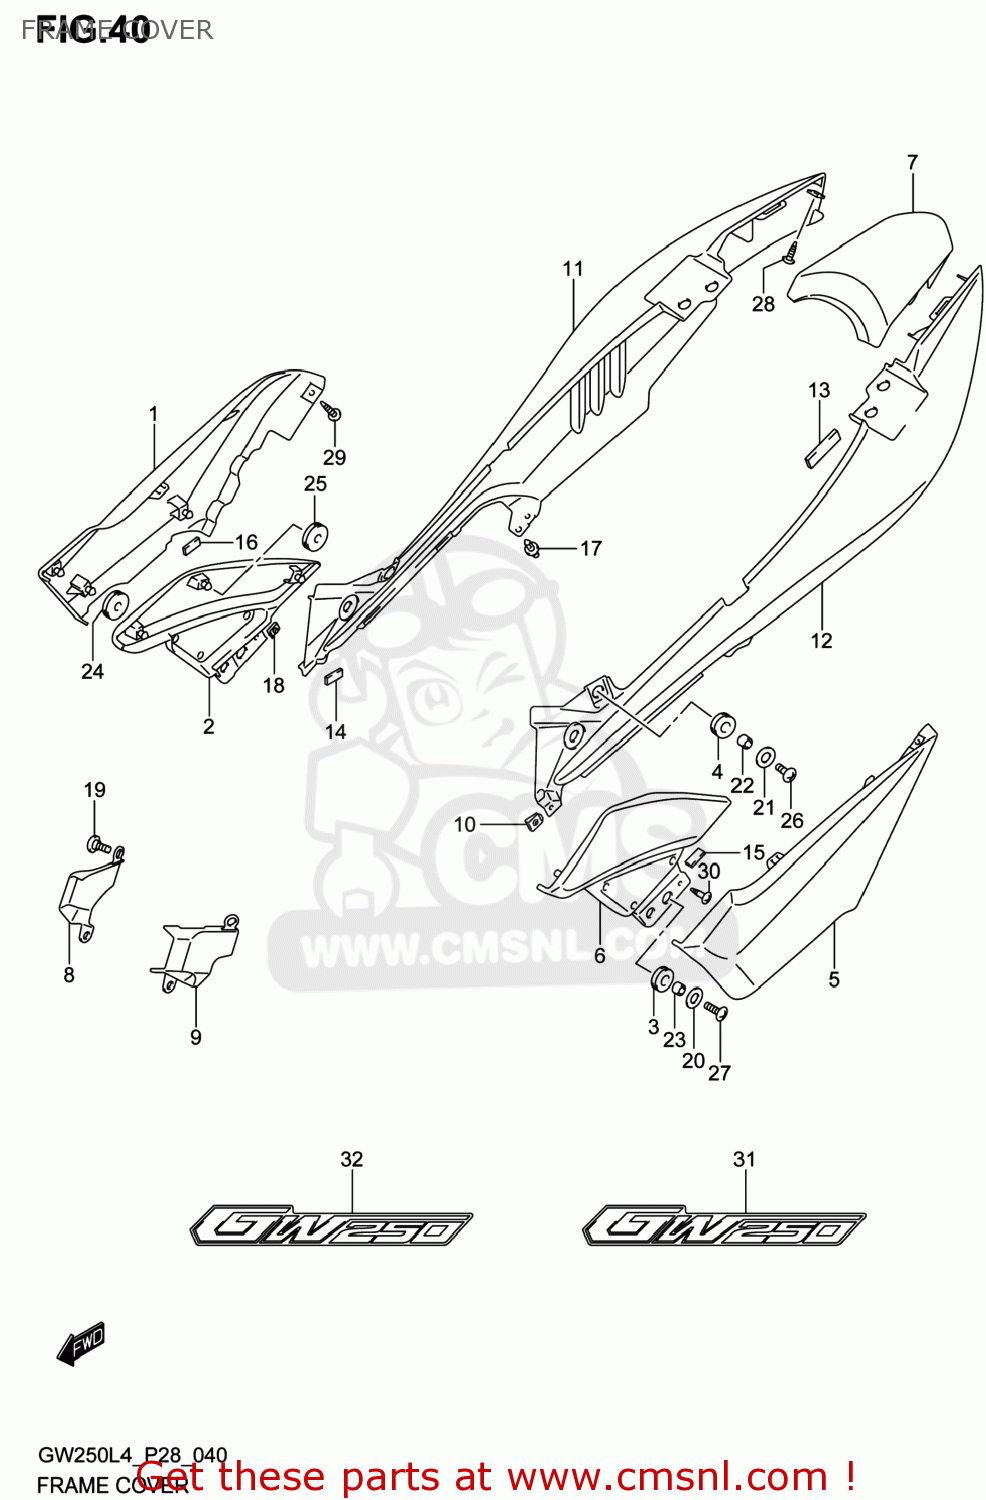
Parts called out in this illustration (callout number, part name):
1	COVER,FRAME,R(BLACK)
2	COVER,FRAME FR,R
3	CUSHION,COVER FR
4	CUSHION,COVER FR
5	COVER,FRAME,L
6	COVER,FRAME FR,L
7	COVER,FRAME UPR CTR
8	COVER,FRAME HEAD,R
9	COVER,FRAME HEAD,L
10	NUT
11	COVER,FRAME UPR,R
12	COVER,FRAME UPR,L
13	CUSHION,FRAME COVER UPR RR
14	CUSHION,COVER UPR
15	CUSHION,COVER UPR
16	CUSHION,COVER UPR
17	CLIP,FRAME COVER
18	NUT
19	SCREW,FRAME HEAD COVER
20	WASHER(6.5X20X1.2)
21	WASHER(6.5X20X1.2)
22	SPACER(6.5X10X7)
23	SPACER(6.5X10X7)
24	CUSHION
25	CUSHION
26	SCREW
27	SCREW
28	SCREW
29	SCREW
30	SCREW
31	EMBLEM,FRAME COVER,R
32	EMBLEM,FRAME COVER,L
